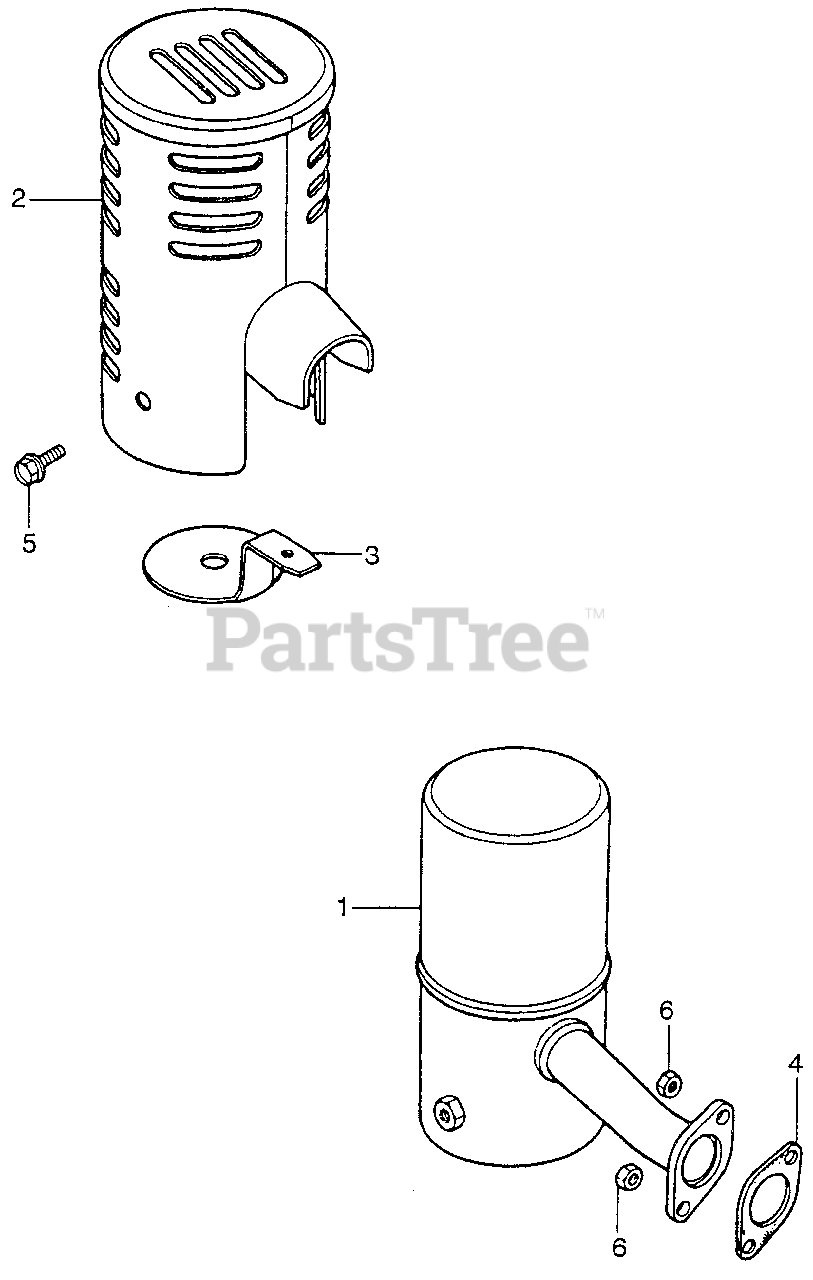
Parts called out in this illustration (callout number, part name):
1	MUFFLER (NOT AVAILABLE)
2	PROTECTOR, MUFFLER (NOT AVAILABLE)
3	PLATE, MUFFLER (LOWER) (NOT AVAILABLE)
4	GASKET, MUFFLER
5	BOLT, HEX. (6X6)
6	NUT, HEX. (6MM)
